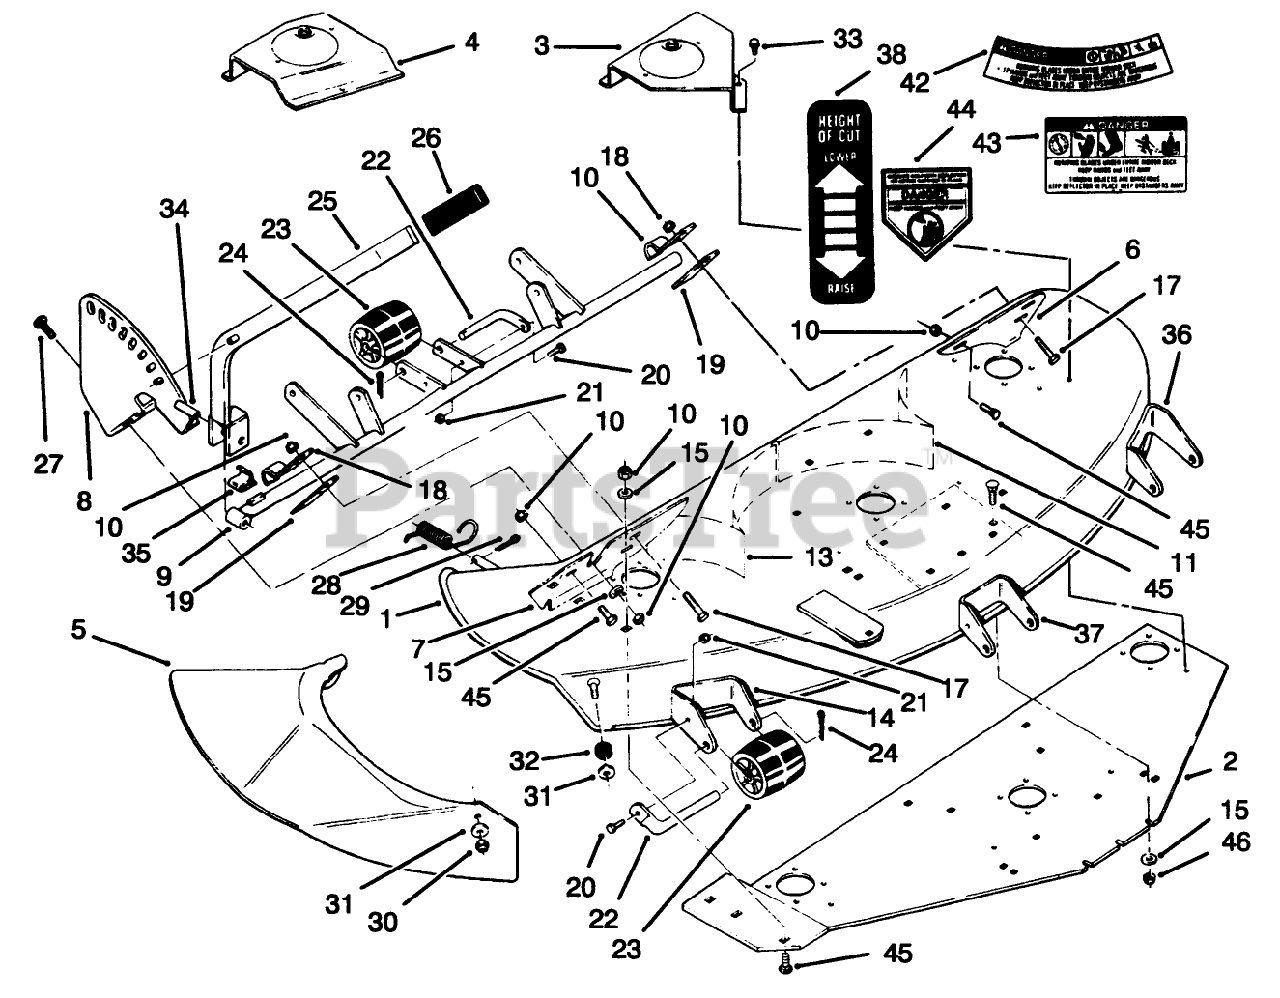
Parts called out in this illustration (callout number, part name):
1	42" DECK WA W/DECALS
2	Plate-Support
3	Belt Cover LH
4	Belt Cover RH
5	Chute Ass-y (Incl. Ref. #44)
6	PLATE-WEAR L.H. R
7	Plate-Wear
8	Quadrant
9	Support-Lift
10	NUT-LOCK, NI
11	BAFFLE-DECK LH
13	BAFFLE-DECK RH
14	BRKT-ROLLER R
15	WASHER-FLAT
17	SCREW-CARR
18	Clamp
19	Bar
20	SCREW-HH
21	NUT-LOCK, NI
22	ROLLER-SHAFT
23	Roller
24	PIN-COTTER
25	Lever
27	BOLT-CARR
28	Spring
29	PIN-COTTER
30	Nut
31	Washer
32	BUSHING-PIVOT
33	SCREW-HWH
34	SPIROL PIN
35	CLIP-SPRING
36	BRKT-ROLER R
37	BRKT-ROLLER
38	DECAL-HOC
42	DECAL - DANGER
43	DECAL-DANGER, THROWN OBJECT
44	DECAL-DANGER
45	BOLT-CARR
46	NUT-LOCK, NI
